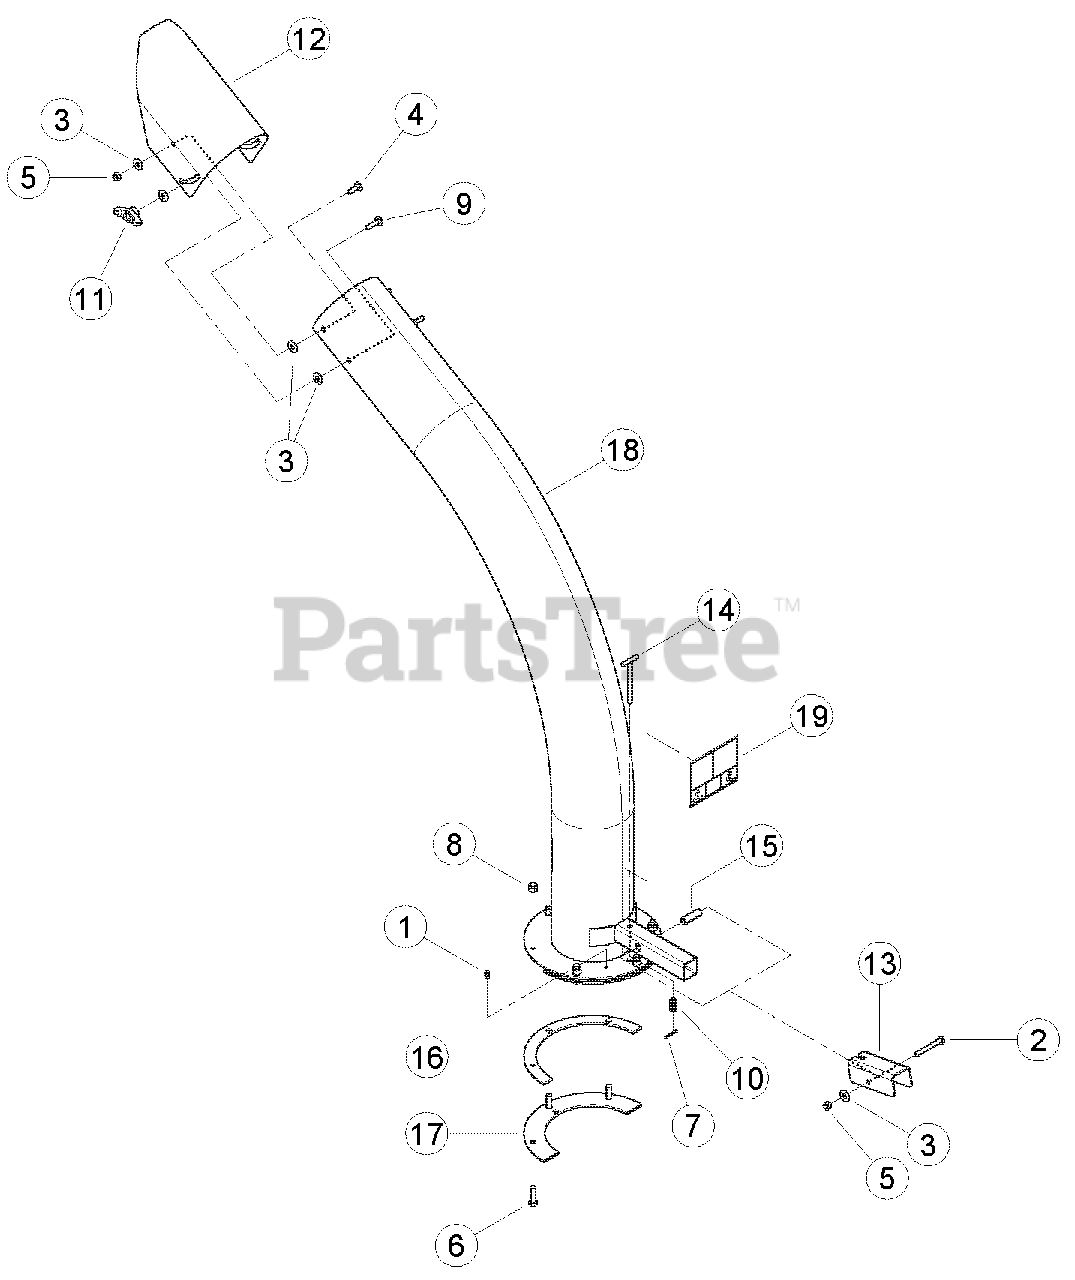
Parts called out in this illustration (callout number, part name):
1	FITTING, 1/4 SELF-TAP GREASE
2	BOLT, 5/16 X 2-1/2 HEX HD GR5 ZP
3	WASHER, 5/16 FLAT ZP
4	BOLT, 5/16 X 1 CRG GR5 ZP
5	NUT, 5/16 NE NYLOCK ZP
6	BOLT, 3/8 X 1-1/4 HEX HD GR5 ZP
7	PIN, 1/8 X 1.00 COTTER ZP
8	NUT, 3/8 NE NYLOCK ZP
9	BOLT, 5/16 X 1-1/4 CRG GR5 ZP
10	SPRING, LOCK COMPRESSION
11	KNOB, 5/16-18 UNC TEE W/LOCKING INSERT
12	DEFLECTOR, BLOWER-VAC DISCHARGE
13	LEVER, DISCHARGE LOCK
14	WELDMENT, DISCHARGE LOCK PIN
15	TUBE, DISCHARGE LOCK PIVOT
16	SPACER, DISCHARGE PIVOT
17	RING, DISCHARGE CLAMP
18	ASSEMBLY, 6 INCH DISCHARGE SERVICE PART
19	DECAL, DISCHARGE DEBRIS & LOCK
